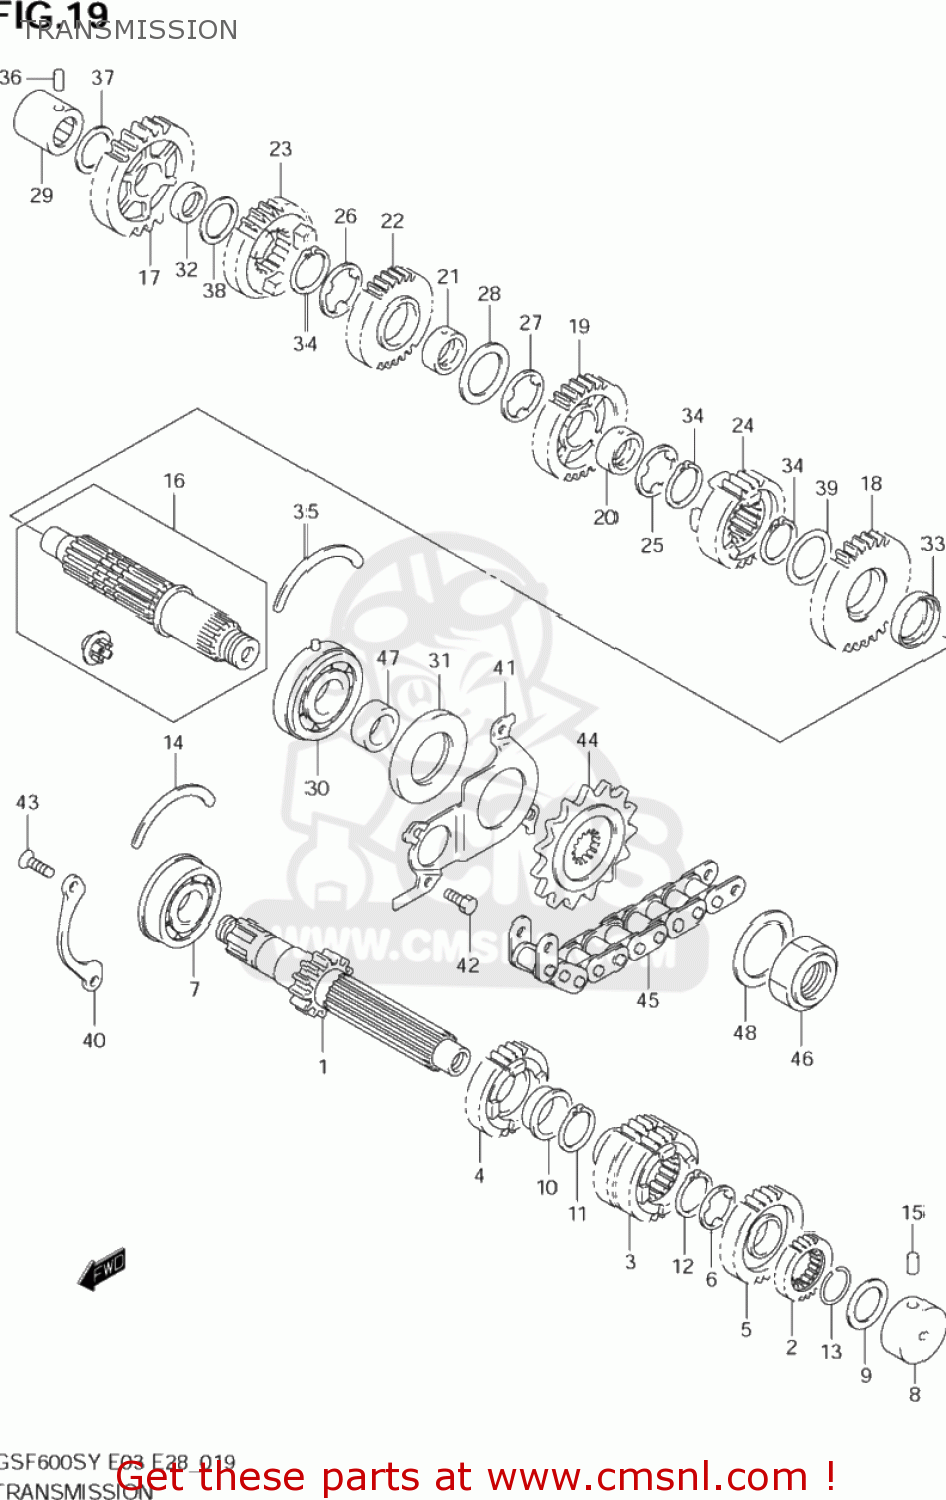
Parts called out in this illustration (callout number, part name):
1	SHAFT,COUNTER(NT:12)
2	GEAR,2ND DRIVE(NT:16)
3	GEAR,3RD & 4TH DRIVE(NT:17/20)
4	GEAR,5TH DRIVE(NT:22)
5	GEAR,6TH DRIVE(NT:21)
6	WASHER,LOCK
7	BEARING(25X62X17)
8	BEARING(20X34X17.5)
9	SEAL,OIL(20X31.2X2.7)
10	BUSHING
11	RING,SNAP
12	RING,SNAP
13	CIRCLIP
14	C RING
15	PIN
16	SHAFT,DRIVE
17	GEAR,1ST DRIVEN(NT:37)
18	GEAR,2ND DRIVEN(NT:33)
19	GEAR,3RD DRIVEN(NT:28)
20	BUSH
21	BUSH
22	GEAR,4TH DRIVEN(NT:28)
23	GEAR,5TH DRIVEN(NT:27)
24	GEAR,6TH DRIVEN(NT:23)
25	WASHER,LOCK
26	WASHER,LOCK
27	WASHER,LOCK
28	WASHER
29	BEARING(20X34X20)
30	BEARING(25X62X21.6)
31	SEAL,OIL(34X62X6)
32	BUSH(22X26X9)
33	BUSH(28X32X9.5)
34	CIRCLIP
35	C RING
36	PIN
37	SHIM(20X34X1)
38	SHIM(22X34X1)
39	SHIM(28X38X1)
40	RETAINER,CNTR SHAFT BEARING
41	RETAINER,DRIVE SHAFT OIL SEAL
42	BOLT
43	SCREW ,6X16
44	SPROCKET,ENGINE(NT:15)
45	CHAIN ASSEMBLY RK FS50MF0Z
46	NUT
47	SPACER(25X34X17.5)
48	SHIM(25X40X1.5)
